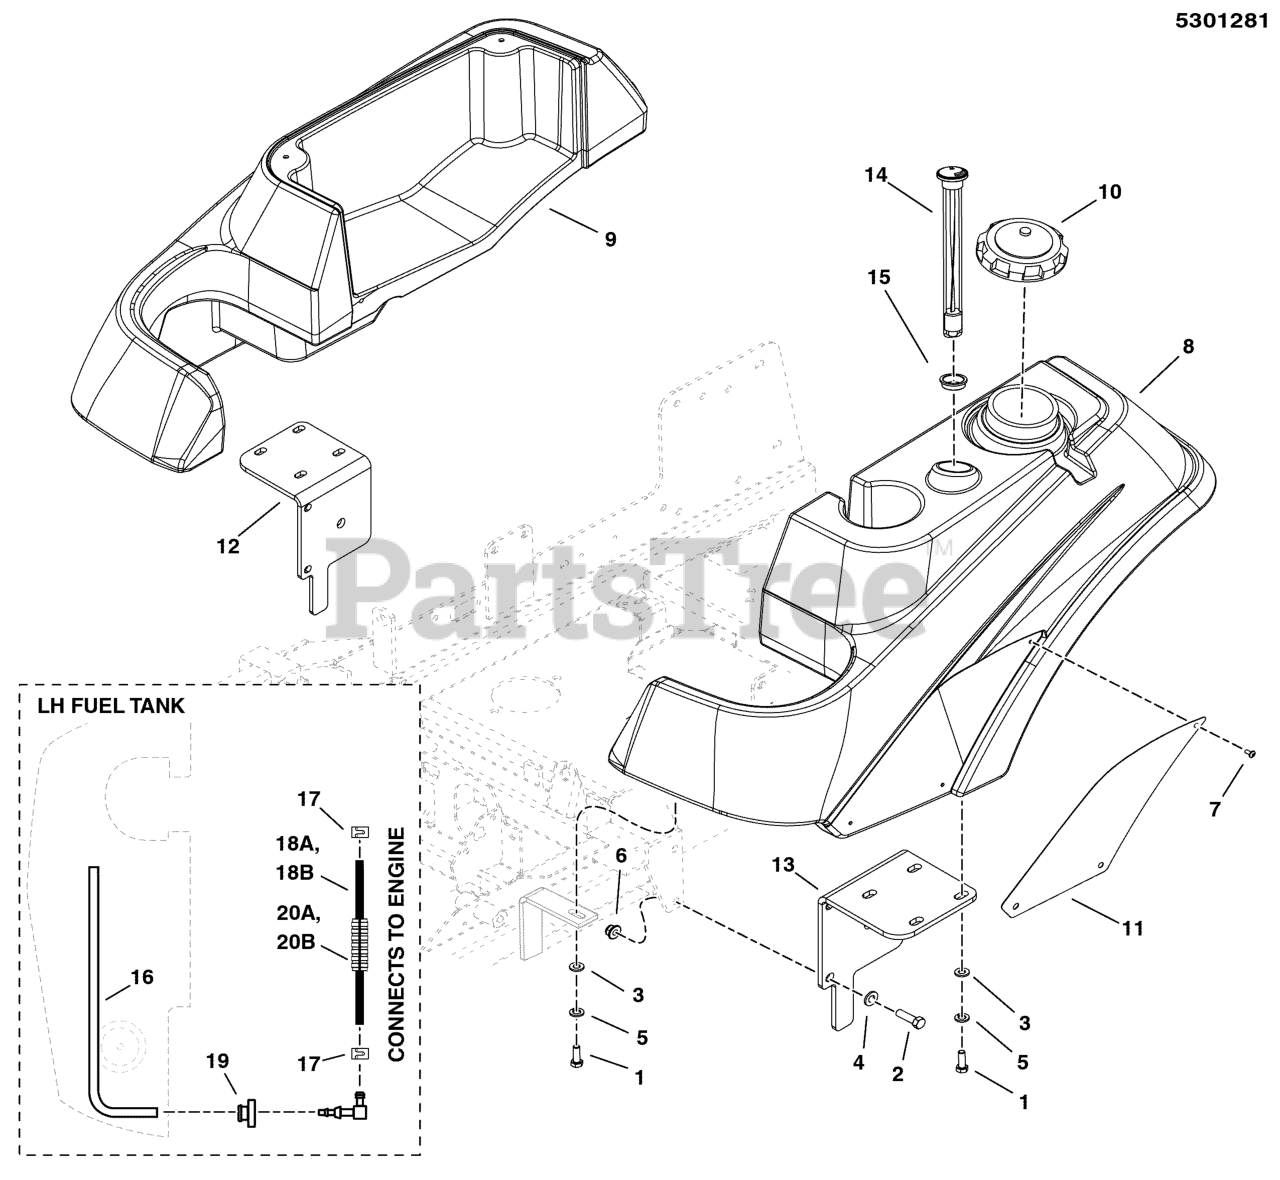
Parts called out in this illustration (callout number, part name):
1	BOLT, 5/16-18 X 1" GRD5 YZ
2	BOLT, 3/8-16 X 1" GD5 CZ
3	WASHER, 5/16" SAE
4	WASHER, 3/8 SAE
5	WASHER, 5/16 LOCK CZ
6	NUT, 3/8 - 16 HEX NYLOCK FLANGE
7	SCREW, Allen Head, #10-24 x 3/8"
8	TANK, FUEL - LH, IS500 & IS1500
9	TANK, FENDER, CITATION/ZT4000 - RH
10	FUEL CAP, 3-1/2", MANAGED VENT OUT, 12"
11	PLATE, BADGE - IS1500 - RED
12	WELD, TANK MOUNT - BLK
13	WELD, TANK MOUNT - LH - BLK
14	GAUGE, FUEL, 12
15	GROMMET, FUEL GAUGE (SV)
16	PICKUP TUBE ASM, FUEL TANK, 22"
17	CLAMP, Hose
18A	1/4" Fuel Line, 8" Long
18B	1/4" Fuel Line, 14" Long
19	BUSHING-FUEL TANK RED RUBBER
20A	WIRE LOOM, 1/2 ID X 5 IN
20B	WIRE LOOM, 1/2 ID, 11.00 LONG
